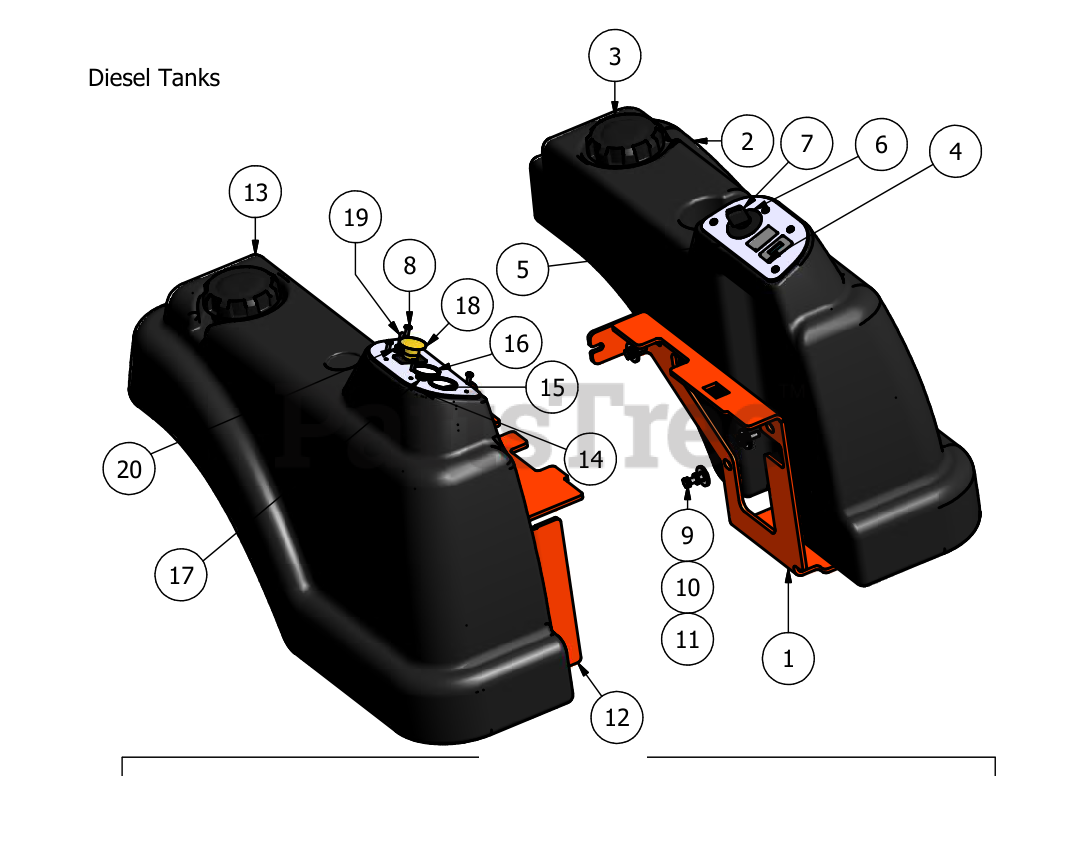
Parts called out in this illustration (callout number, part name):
1	Left Fuel Tank Swing Support
2	Left Fuel Tank with Fender
3	Diesel Fuel Cap
4	Hourmeter-Diesel
5	Control Panel (Left)
6	Ignition Switch
7	Ignition Key
8	10mm x 32 x 1" Bolt
9	5/16" x 1" Hex Bolt
10	5/16" Lock Washer
11	1 5/16" Flat Washer
12	Right Fuel Tank Support
13	Right Fuel Tank with Fender
14	Diesel Control Panel (Right)
16	Temperature Guage
18	PTO Engager
19	Deck Lift Joystick
20	Joystick Cover
